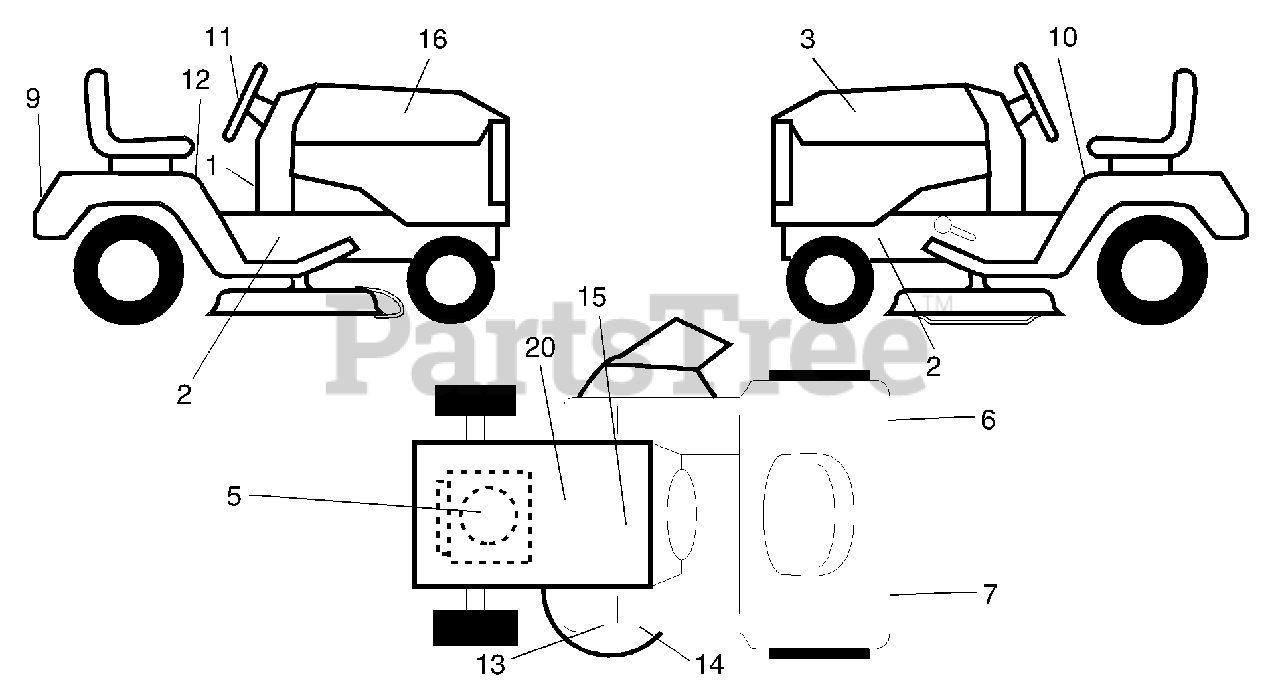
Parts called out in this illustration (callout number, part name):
1	Decal Dash
2	Decal Chassis 25/48 Statesman
3	Decal Hood LH
5	Decal HP Engine
6	Decal Reflector Rh
7	Decal Reflector Lh
9	Decal Fender Logo
10	Decal Fender Danger
11	Decal Ins Strg Whl
12	Decal Fender Oper Cruise
13	Decal Deck Caution
14	Decal V-Belt Schematic
15	Decal Replace
16	Decal Hood Rh
20	Decal Bat Dan/Psn
